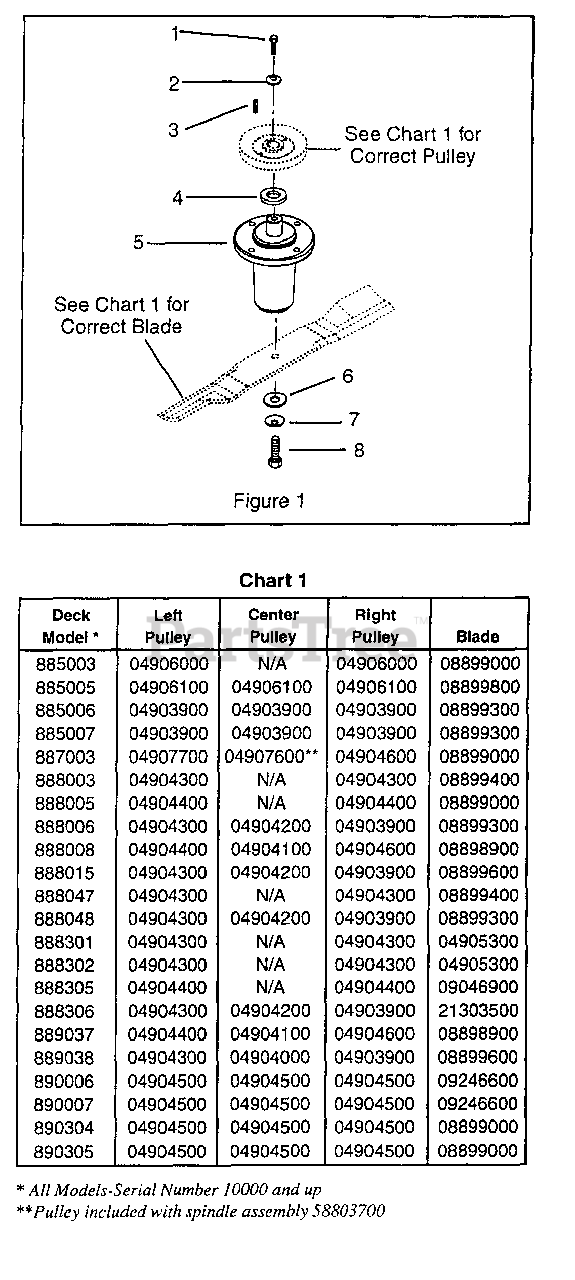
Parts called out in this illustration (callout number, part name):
1	Bolt-Hex.38-16 x 1.00 Grade 8
2	Washer-Cupped-Serrated .375
3	Key-Straight .25 x 1.00 x .25
4	Slinger-Dust
5	Assembly-Spindle
6	Washer-Flat.640 x 1.81 x .250
7	Washer-Bellville .63 x 1.625 x .14
8	Bolt-Blade
